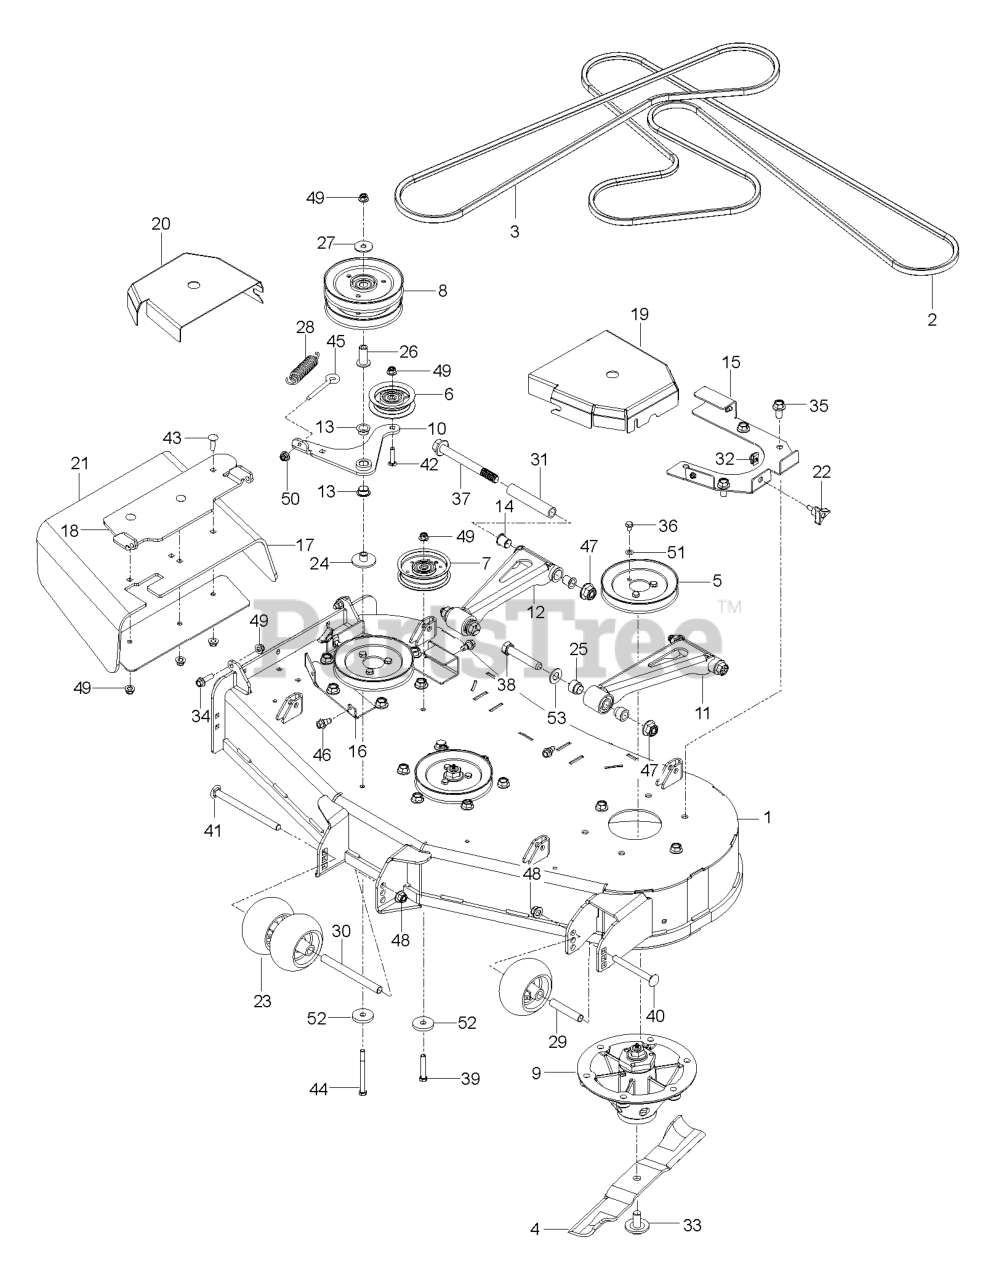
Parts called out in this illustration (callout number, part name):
1	DECK.ASM.WLD.48CCC.STANDON.668
2	BELT STANDON 48 CCC DECK
3	BELT.DECK.DRIVE.STAND-ON
4	BLADE STANDON 48 CCC DISCHARGE
5	PULLEY - 6.57
6	PULLEY.IDLER.FLAT.3.06"
7	PULLEY.IDLER.FLAT.4"
8	Bearings
9	SPINDLE.ASSY.IRON
10	ARM STANDON WELDMENT; DECK TEN
11	ARM STANDON LH DRAWBAR WELDMEN
12	ARM STANDON 54 CCC RH DRWBR
13	BEARING FLANGED; PLASTIC 5/8"
14	BEARING FLANGED;PLASTIC 7/8" I
15	BRACKET STANDON 48 CCC LH PULL
16	BRACKET STANDON 48 CCC RH PULL
17	BRACKET STANDON LOWER DEFLECTO
18	BRACKET STANDON UPPER DEFLECTO
19	COVER STANDON 48 CCC LH PULLEY
20	COVER STANDON 48 CCC RH PULLEY
21	DEFLECTOR STANDON MOLDED DECK
22	KNOB W/STUD
23	ROLLER, GAUGE .635 BORN
24	SPACER STANDON DECK TENSIONER
25	SPACER STANDON DRAWBAR BEARING
26	SPACER STANDON STACKED PULLEY
27	SPACER STANDON STACKED PULLEY
29	TUBE, ROLLER AXLE
30	TUBE, ROLLER AXLE LONG
31	TUBE STANDON DRAWBAR SPACER
32	U-CLIP 5/16-18 NUT RETAINER
33	BLADE BOLT/WASHER
34	HHFS 3/8-16 X 1.25 GD 5
35	HHFS 1/2-13 X 1 GR5 ZD
36	HCS 5/16-18 X 1/2 GR 5 ZD
37	BOLT HEXAGON HEAD WITH FLANGE
38	5/8-11 X 3-1/2 HHB GRADE 5
39	BOLT.HEX
40	RHSNB 1/2-13 X 4.75 GR5 ZD
41	RHSNB 1/2-13 X 8 GR5 ZD
42	RHSNB 3/8-16X1-3/4
43	BOLT.3/8-14X1.25
44	BOLT HEXAGON HEAD 3/8-16 X 4-1
45	EYE BOLT 5/16 X 3.50
46	BOLT.SHOULDER
47	NUT 5/8-11 FLG NYLOC ZD
48	NUT, 1/2-13 HEX FLG NYLOC ZD
49	NUT 3/8-16 HEX FLG NYLOC ZD
50	5/16-18 NYLOC FLANGE NUT
51	WASH 5/16 DISC SPRING ZD
52	SPINDLE WASHER
53	WASHER
